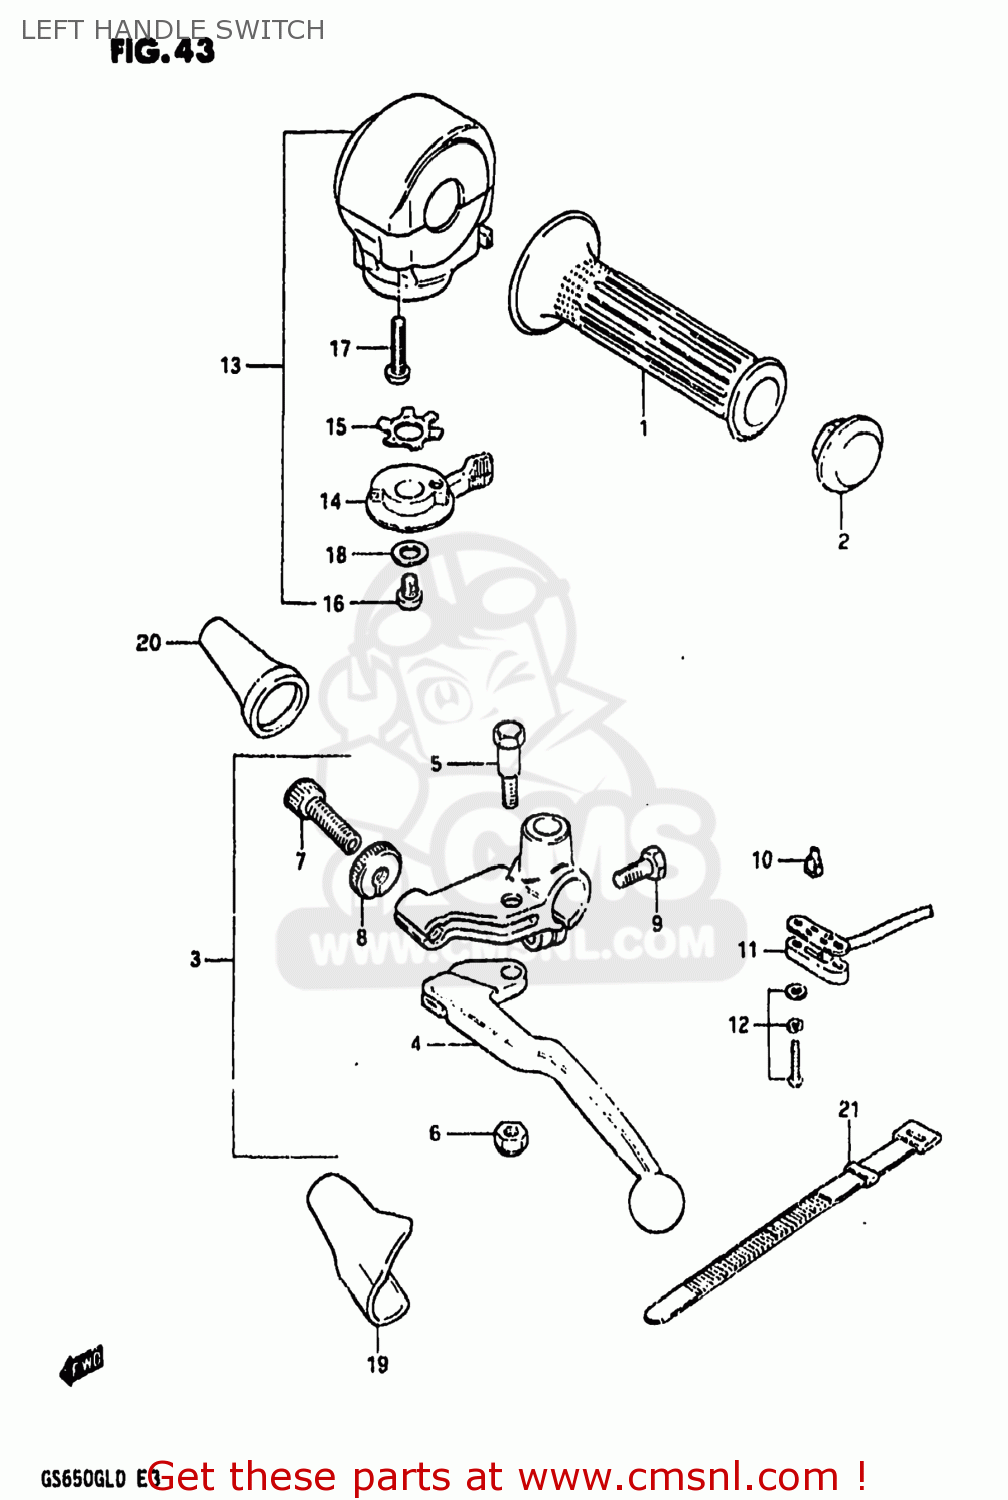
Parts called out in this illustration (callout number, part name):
1	GRIP,LEFT
2	CAP,GRIP END
3	LEVER ASSEMBLY
4	LEVER,CLUTCH
5	BOLT,LEVER
6	NUT 6MM
7	ADJUSTER,CABLE
8	NUT,CABLE ADJUSTER
9	BOLT,CLUTCH LEVER HOLDER
10	CONTACT,SWITCH
11	COVER,FR BK TERMINAL BASE
12	SCREW
13	SWITCH ASSEMBLY,HANDLE,LEFT
14	LEVER,STARTER
15	WASHER
16	SCREW
17	SCREW
18	WASHER 6MM
19	COVER,CLUTCH LEVER
20	BOOT,CLUTCH CABLE
21	CLAMP(L:120)
